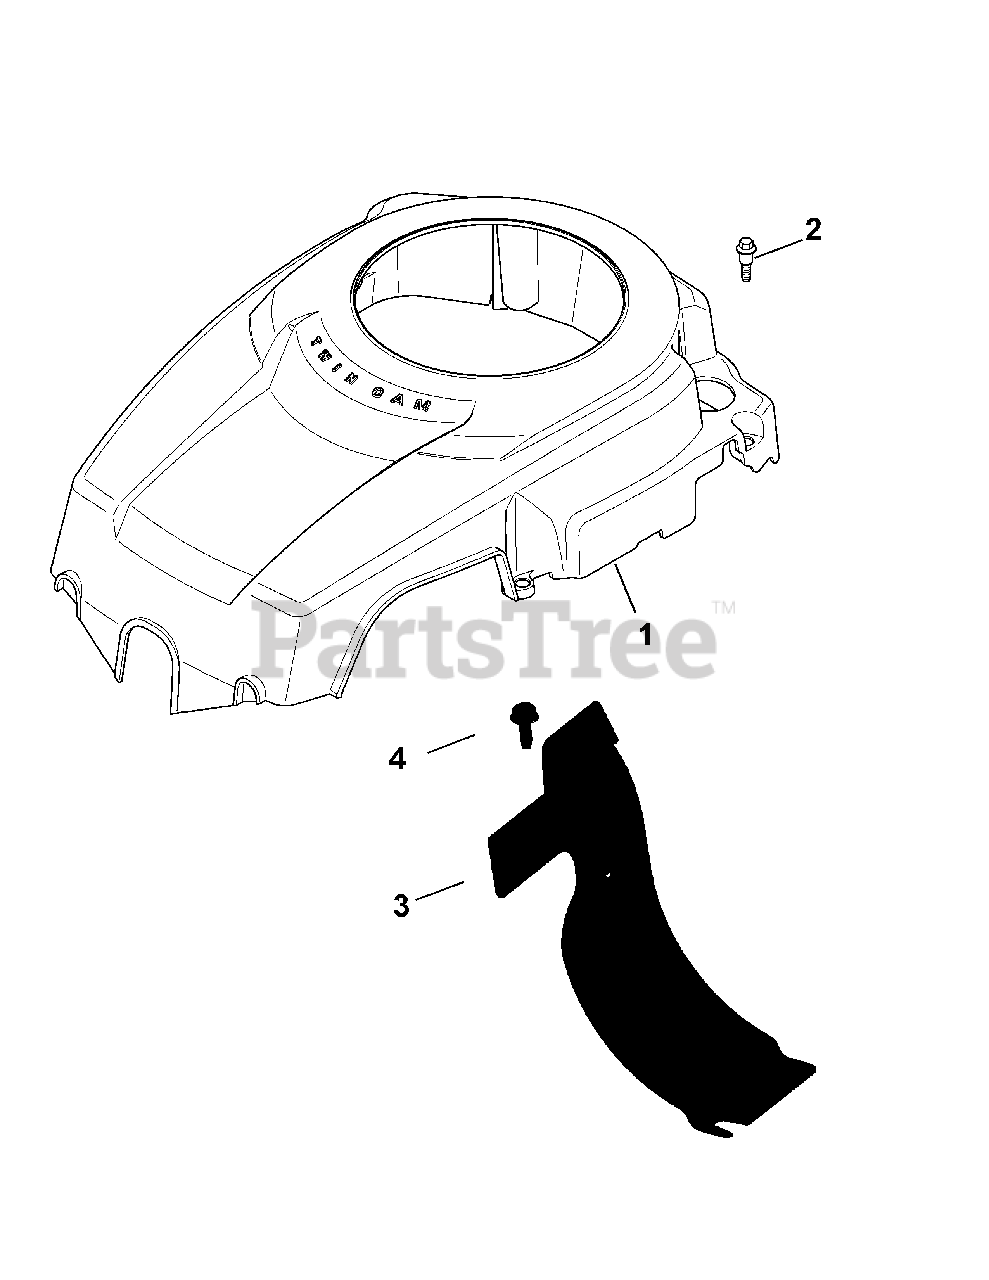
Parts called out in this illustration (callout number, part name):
1	Blower Housing
2	Shd. Thd. Frm. Screw, M6 X 1 X 26
3	Baffle Barrel
4	Thread Forming Screw
